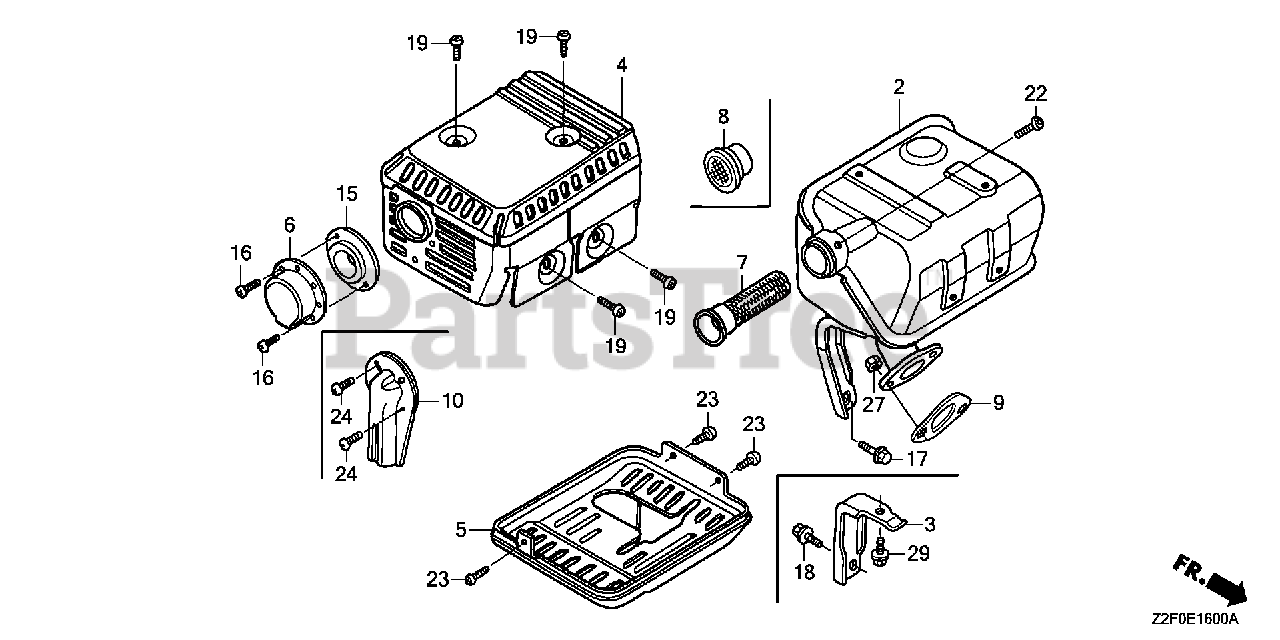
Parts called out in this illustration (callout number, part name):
2	MUFFLER (ARRESTER)
4	PROTECTOR, MUFFLER (STD) (BLACK)
7	ARRESTER, SPARK
9	GASKET, MUFFLER
19	SCREW, TAPPING (5X8)
22	SCREW, TAPPING (4X6)
27	NUT, HEX. (8MM)
